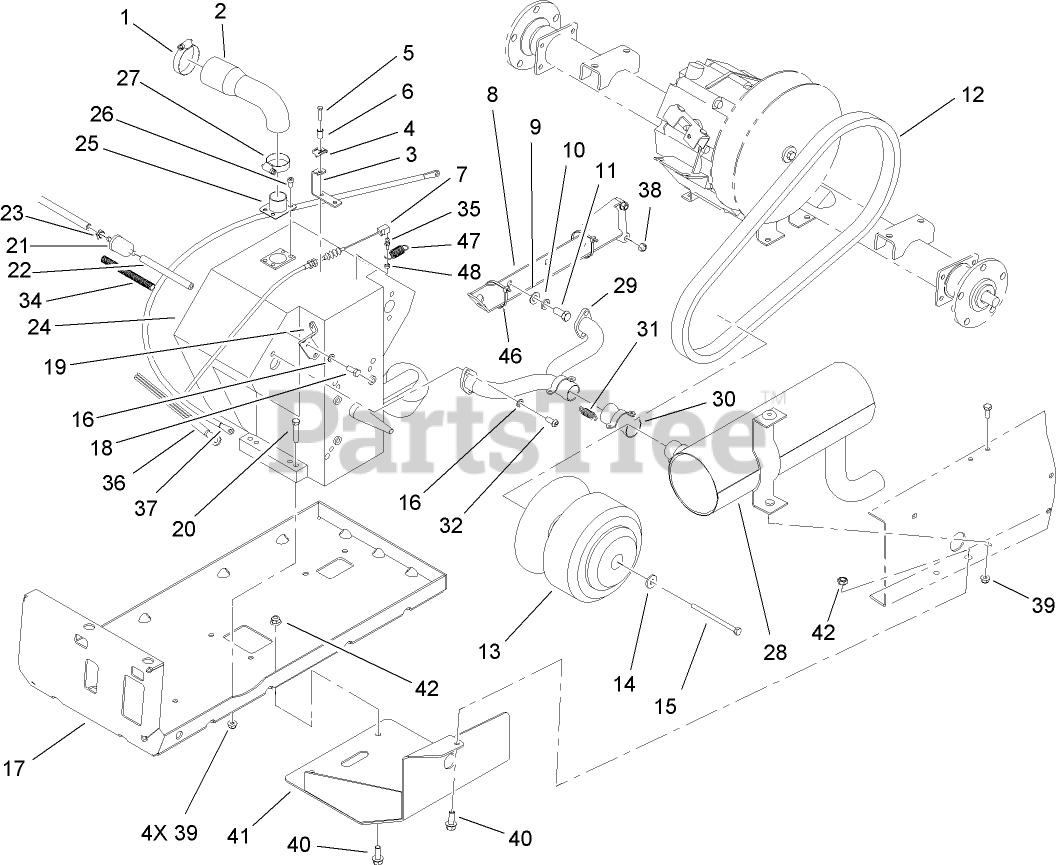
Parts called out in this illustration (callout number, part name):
1	CLAMP-HOSE
2	HOSE-INTAKE
3	BRACKET-CABLE
4	CLAMP-CABLE
5	SCREW-HH
6	NUT-CLINCH
7	CABLE-ACCELERATOR
8	TORQUE ARM ASM
9	WASHER-FLAT
10	WASHER-LOCK
11	SCREW-HH
12	BELT-DRIVE
14	WASHER
15	SCREW-HH
16	WASHER-LOCK
17	MOUNT-ENGINE
19	BRACKET-CABLE, THROTTLE
20	SCREW-HH
21	FILTER-FUEL
22	HOSE-FUEL
23	CLAMP-HOSE
25	BRACKET-INTAKE
26	SCREW-HSH
27	CLAMP-HOSE
28	MUFFLER-ENGINE
29	MANIFOLD-ENGINE
30	COUPLER-EXHAUST
31	SPRING-EXTENSION
32	SCREW-HSBH
34	CONDUIT-LINE, FUEL
35	BALL-STUD
36	HARNESS-WIRE, ENGINE
37	POSITIVE WIRE ASM
38	NUT-LOCK, NI
39	NUT-HF, NI
40	SCREW-HHF
41	CLUTCH GUARD ASM
42	NUT-HF, NI
46	TIE-CABLE
47	SPRING-BRAKE
48	KEEPER-SPRING
